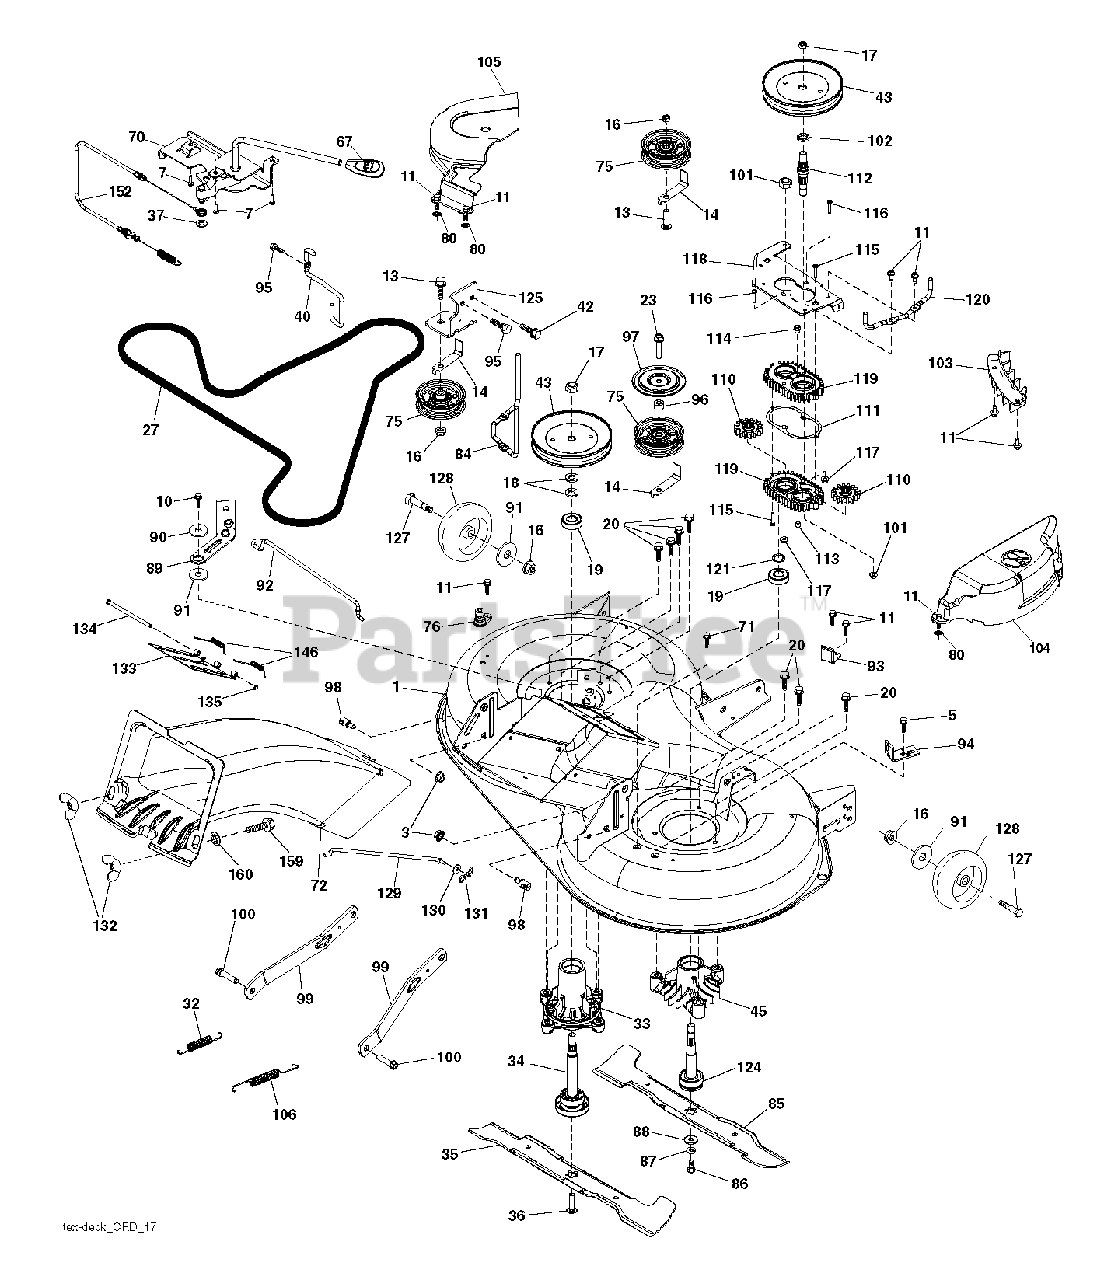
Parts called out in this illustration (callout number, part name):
3	NUT LOCK HEX FLANGE 5/16-18
5	BOLT.5/16HEX.WHS.HD
7	SCREW.#10 X 0.750.BOS THREAD
10	SCREW 3/8-16X1
11	SCREW.1/4-20X5/8
13	BOLT.3/8-16X1.50
14	KEEPER, BELT IDLER
16	NUT LOCK FLG 3/8-16 UNC
17	NUT.FLANGE.LOCK.TOP
18	WASHER.SPACER.MANDREL
20	SCREW, WASHER HEAD
23	SCREW LT
32	SPRING RETURN
33	HOUSING MANDREL
34	SHAFT.ASM.MDRL.N/GREASE.38
35	BLADE.3N1.LH.CRD.97
36	BOLT.WASHER.ASM.7/16-2
40	KEEPER BELT ENGINE LH
42	SCREW
43	PULLEY.MANDREL.5.438.PD
45	HOUSING.MANDREL
67	HANDLE.CLUTCH.CABLE.LT
70	CLUTCH.ASM.MANUAL.YT.PREDATORQ
71	SCREW 3/8-16X1/2
75	FLAT IDLER PULLEY
76	PORT.WASHOUT
80	PALNUT 1/4
84	KEEPER.BELT.MANDREL.PULLEY
85	BLADE.3N1.RH.CRD.97
87	LOCKWASHER
88	WASHER.BLADE
90	SPACER.RETAINER
94	BRKT.CLUTCH.CABLE
95	SCREW, 3/8-16X3/4
98	STUD.FASTNER.W/ANTI-ROTATE
99	ARM.SUSPENSION.MOWER.R
100	BOLT.SHOULDER
102	SPACER BEARING
106	SPRING.BRAKE.RETURN.38"
117	NUT T
127	BOLT.SHOULDER.3/8-16X3-5/8
128	WHEEL. GUAGE RALLY
129	ROD.ANTI.SWAY.48/54"K4
130	WASHER
131	PIN.COTTER.5/16.BOW TI
132	KNOB.HANDLE.3/8.TRI-POINT.BLAC
135	E-RING.5/16"
159	BOLT
